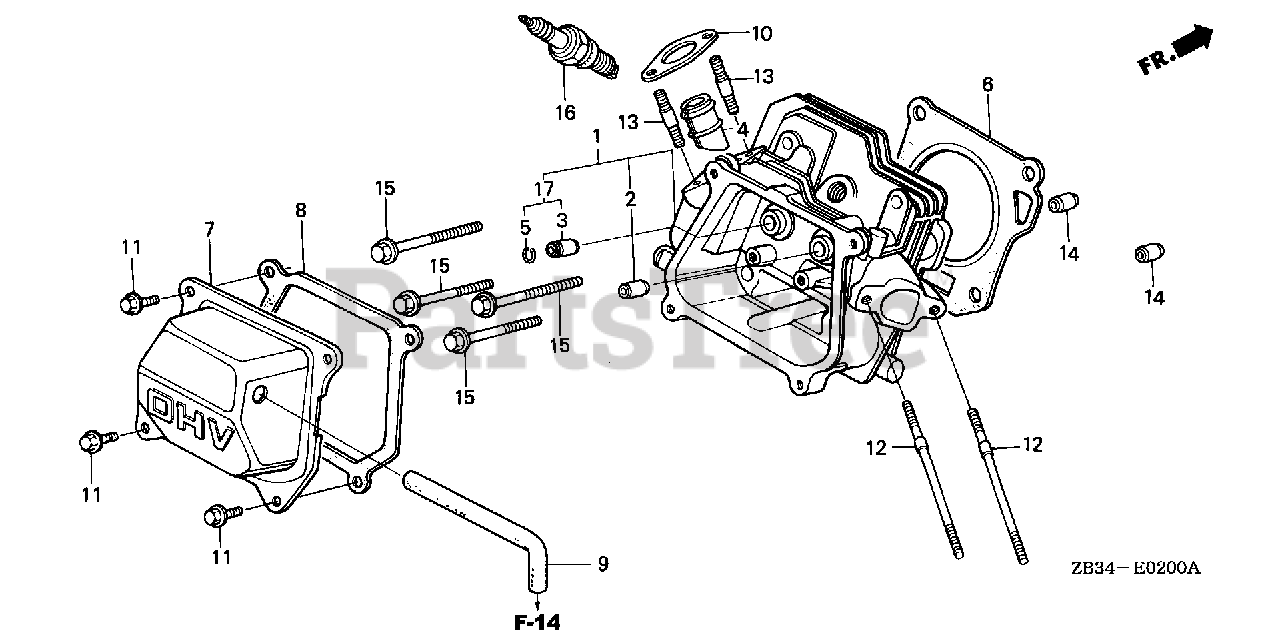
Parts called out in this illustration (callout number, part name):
1	CYLINDER HEAD
2	GUIDE, VALVE (OVER SIZE)
5	CLIP, VALVE GUIDE
6	GASKET, CYLINDER HEAD
7	COVER, HEAD
8	GASKET, HEAD COVER
9	TUBE, BREATHER
10	GASKET, MUFFLER
11	BOLT, FLANGE (6X12) (CT200)
11	BOLT, FLANGE (6X13) (CT200)
12	BOLT, STUD (6X94)
13	BOLT, STUD (8X32)
14	PIN, DOWEL (10X16)
15	BOLT, FLANGE (8X60)
16	SPARK PLUG (BPR6ES) (NGK)
16	SPARK PLUG (W20EPR-U) (DENSO)
17	GUIDE, EX. VALVE (OVER SIZE)
